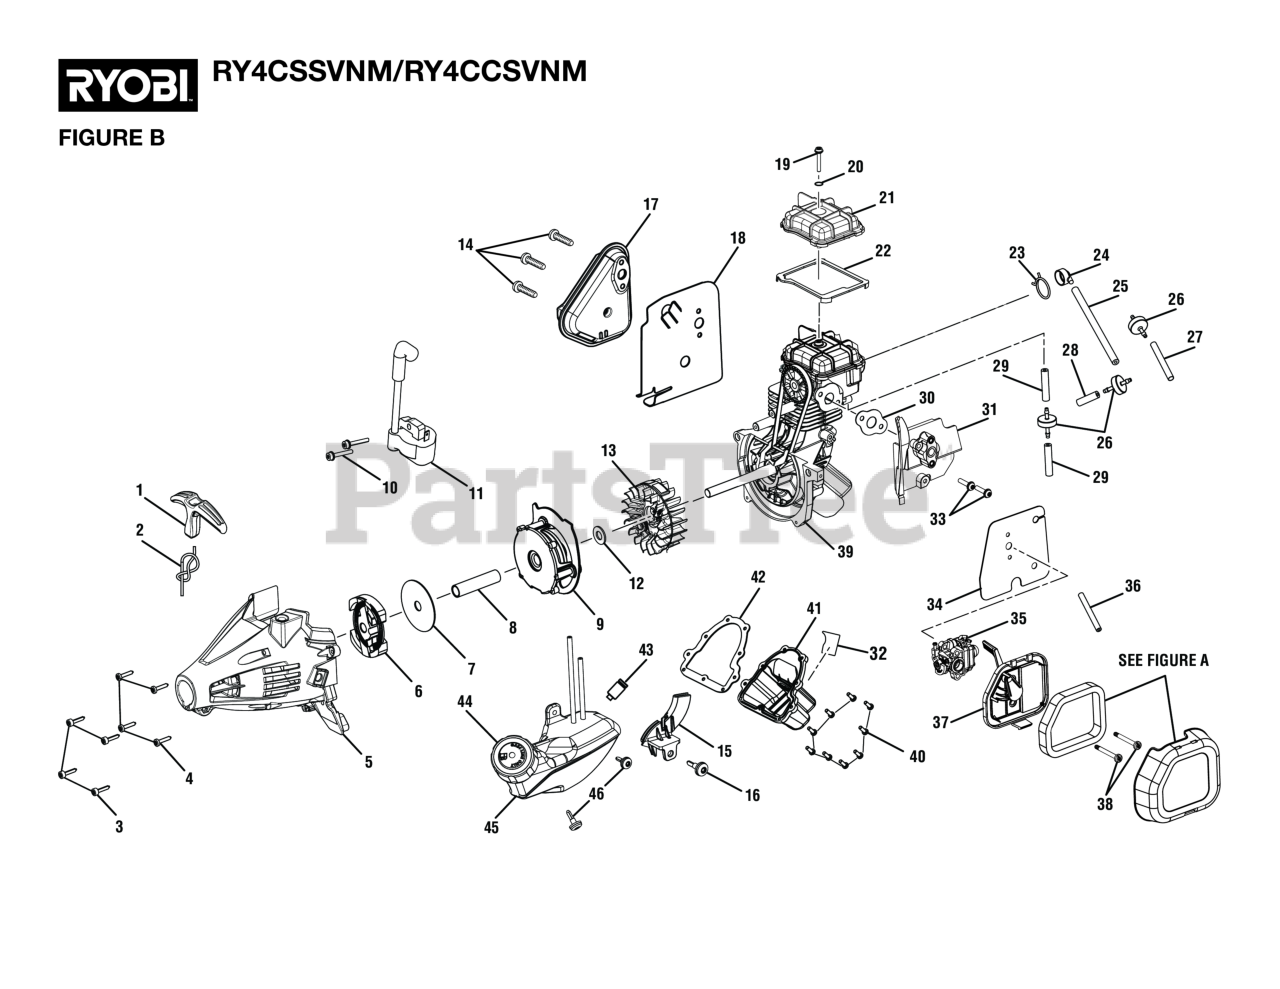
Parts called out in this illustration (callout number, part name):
1	Pulley Handle
2	STARTER ROPE 42 (PKG)
3	Screw (M4 x 18 mm, T20 Torx Pan Hd. S.T.)
4	Screw w/Washer (M4 x 16 mm, T25 Torx Truss Hd.)
5	Starter Housing Assembly
6	CLUTCH ASSEMBLY
7	Washer (ID9.63 x OD50.75 x 1.10t)
8	Spacer Tube
9	Starter Housing Assembly
10	Screw w/Washer (M4 x 19 mm, T20 Torx Pan Hd. S.T.)
11	Ignition Module
12	Washer (ID9.75 x OD20 x 1.6t)
13	Flywheel Assembly
14	Screw (M5 x 42 mm, T25 Torx Truss Hd.)
15	Throttle Cable Guide
16	Shoulder Screw (M4 x 19 mm, T25 Torx Truss Hd.)
17	Muffler Assembly
18	Muffler Gasket
19	Screw (M4 x 27 mm Total, w/14 mm Threaded)
21	Cam Cover
22	Cam Cover Gasket
23	Wire Clamp
24	Breather Fitting
25	Breather Hose (120 mm)
26	Check Valve
27	Shield Sleeve (M6 x 50 mm)
28	Breather Hose (24 mm)
29	Breather Hose (34 mm, Crankcase)
30	Heat Dam Gasket
31	Heat Dam
32	Hot Surface Label
33	Screw (M5 x 23 mm, T25 Torx Pan Hd.)
34	Heat Shield w/Gasket (Carburetor)
35	Carburetor
36	Breather Hose (50 mm)
37	Air Box Base Assembly
38	Screw (M5 x 44 mm,T25 Torx Hd. Carburetor)
39	Short Block Assembly
40	Screw (M4 x 12 mm, T20 Torx Hd.)
41	Oil Pan (Inc. Key No. 47)
42	Oil Pan Gasket
43	Fuel Filter
44	Fuel Cap Assembly
45	Fuel Tank w/Cap (Inc. Key Nos. 43-44)
46	Shoulder Screw w/Washer (M4 x 14 mm, T25 Torx Truss Hd.)
